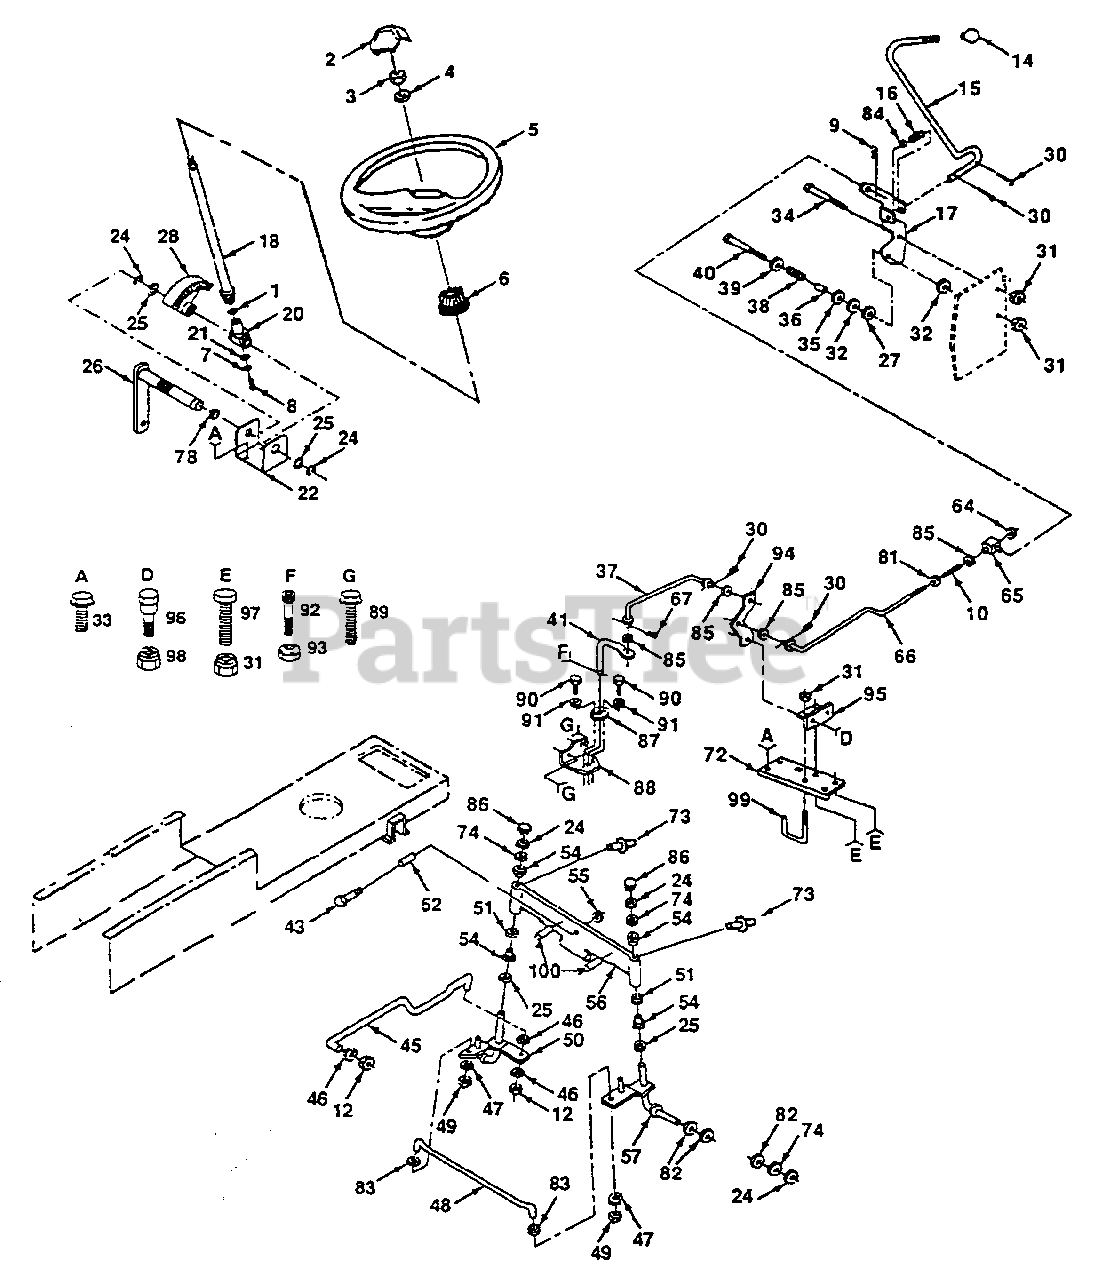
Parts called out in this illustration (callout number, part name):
2	Insert, Steering Wheel
3	Nut, Toplock, Jam 1/2-20
5	Wheel, Steering
6	Adapter, Steering Wheel
7	Washer, Lock 1/4
8	Screw, Hex, Socket 1/4-20 x 5/8
9	Spring, Retainer
10	Spring, Compression
12	Nut, Hex, Fin 3/8-24 UNF
14	Knob, Gearshift
16	Spring, Torsion
17	Bracket, Control Rod
18	Shaft, Steering
20	Support, Shaft
21	Washer, Shim 1/4 x 5/8 x .062
22	Bracket, Steering
25	Bearing, Thrust
26	Shaft, Pitman
27	Washer, Phenolic
30	Pin, Cotter 1/8 x 3/4
31	Nut, Crownlock 3/8-16
32	Washer, Friction
33	Screw, Hex, Washer Thrdrol. 3/8-16 x 3/4
34	Bolt, Hex, Shoulder 3/8-16 x 1-3/8
35	Washer 21/32 x 1-1/4 x 16 Gauge
37	Link, Control, Pump
38	Spring, Compression
39	Washer 13/32 x 1-1/4 x 12 Gauge
40	Bolt, Hex 3/8-16 x 3
41	Lever, Pump Control
43	Bolt, Hex 5/8-11 x 3-1/2
46	Washer, Lock 3/8
47	Washer, Lock 5/16
48	Rod, Tie
49	Nut, Hex 5/16-24 UNF
50	Spindle, L.H.
51	Washer 27/32 x 1-1/4 x 16 Gauge
52	Spacer, Bearing
54	Bearing
55	Locknut, Flange 5/8-11
57	Spindle, R.H.
64	Locknut, Hex w/Washer Insert 3/8-16 UNC
66	Rod, Control, Adjustable
67	Clip, Hairpin
68	Tube (Optional, Service Part)
72	Bracket, Chassis, Reinforcement, Hydro
73	Fitting, Grease
74	Washer 25/32 x 1-5/8 x 16 Gauge
78	Nyliner, Snap In
81	Washer 13/32 x 3/4 x 12 Gauge
82	Washer 25/32 x 1-1/4 x 16 Gauge
83	Washer 11/32 x 3/4 x 16 Gauge
84	Washer 15/32 x 15/16 x 16 Gauge
85	Washer, Spring
87	Guide, Control
88	Bracket Control Guide
89	Screw, Hex, Washer Thrdrol. 5/16-18 x 3/4 Type TT
90	Screw, Hex Tap #10-24 UNC x .625
91	Washer 7/32 x 1/2 x 16 Gauge
92	Screw, Hex, Socket Head #10-24 UNC
93	Locknut #10-24 UNC
95	Bracket, Bellcrank Pivot
96	Bolt, Shoulder
97	Bolt, Hex, Fin 3/8-16 UNC x 1
98	Nut, Crownlock 3/8-16 UNC x 1
99	Keeper, Centerspan
